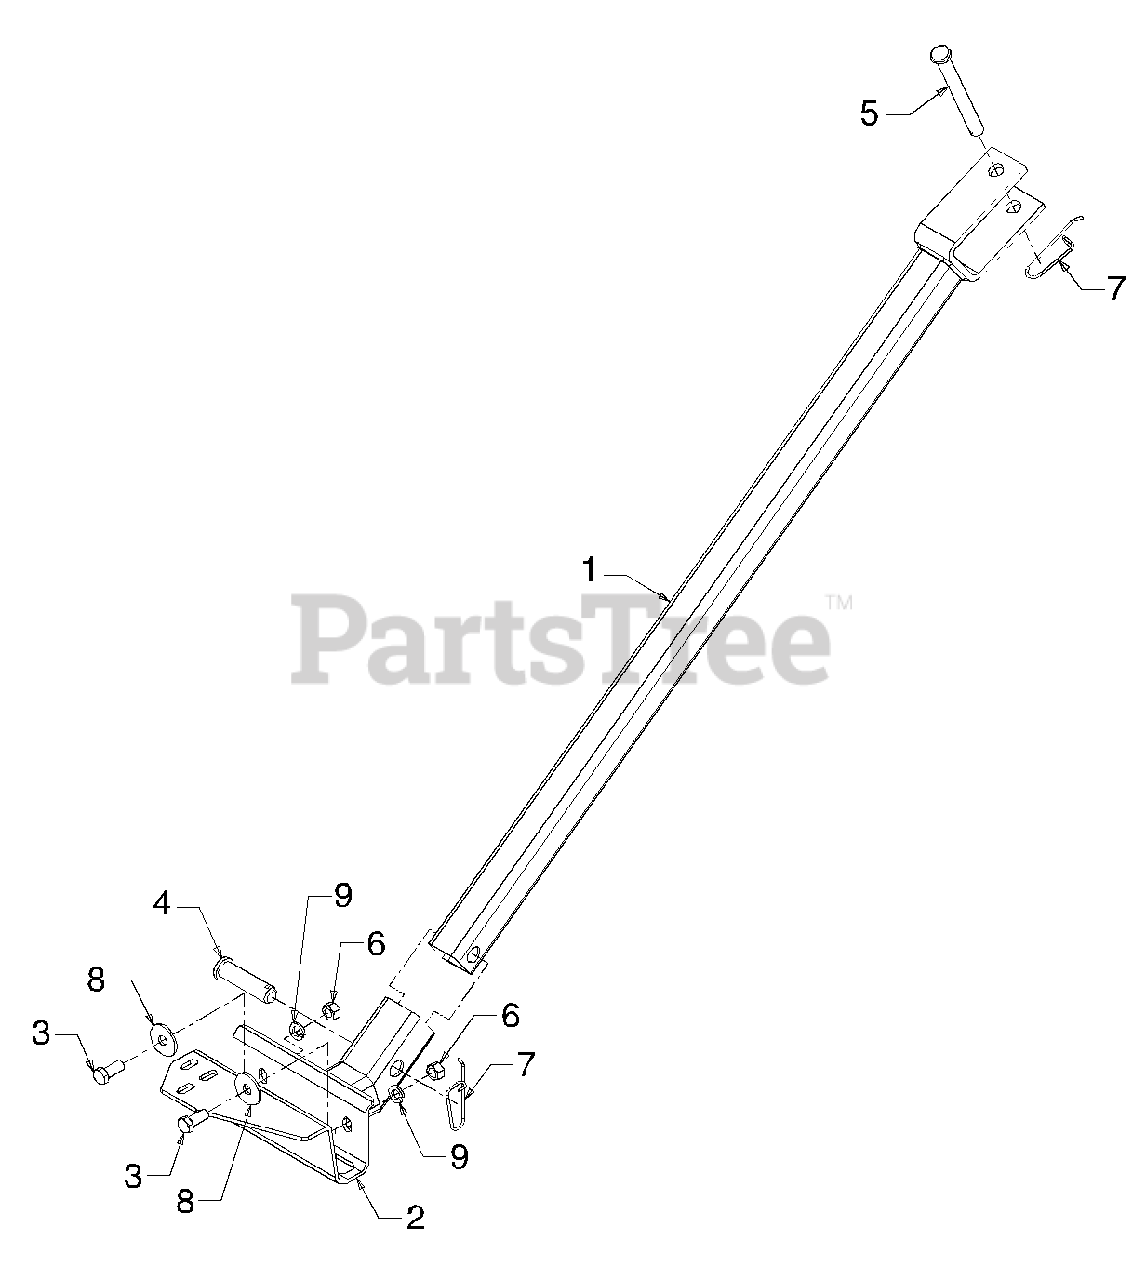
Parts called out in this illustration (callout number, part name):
3	Hex Hd. Cap Scr. 3/8-16:.880 Lg.
4	Pin, Clevis - .625 x 2.40 Lg.
5	Pin, Clevis - .500 Dia. x 4.62 Lg.
6	Hex Nut 3/8-16
7	Spring Pin
8	Fl. Wash. .411 x 1.25 x 1.00
9	Lock Wash. 3/8 Reg.
